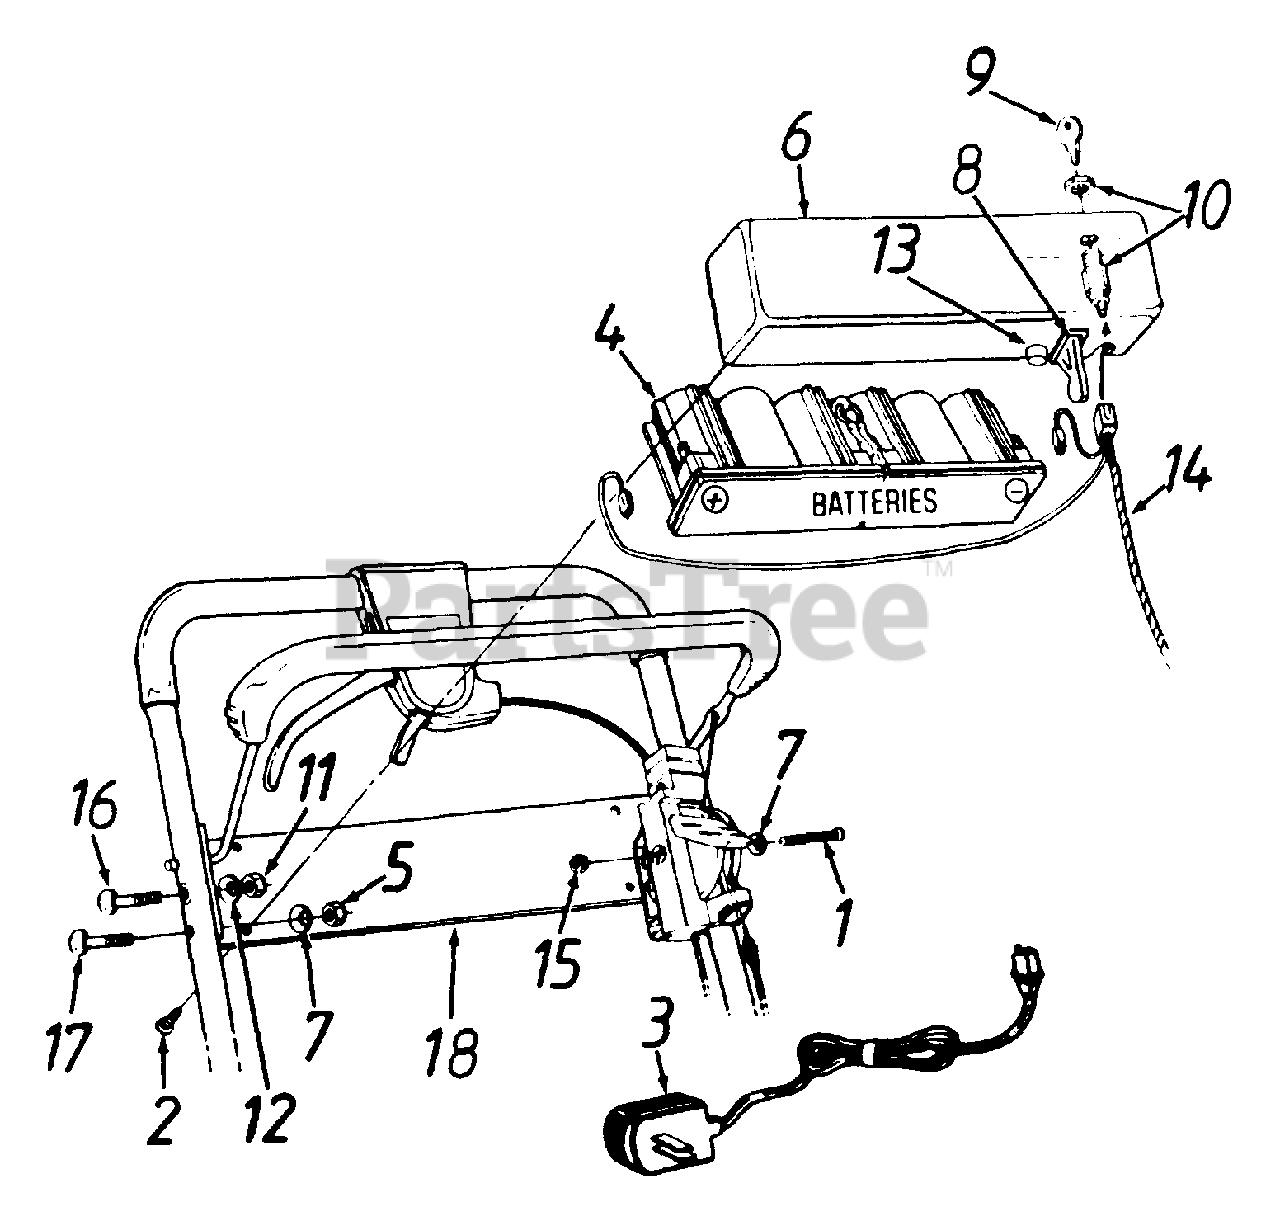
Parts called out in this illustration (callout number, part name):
1	Hex Bolt 1/4-20 x 2" Lg.
2	Truss Mach. Hi-Riser Tap Scr. 1" Lg.
3	Battery Charger
4	Battery Pack - 12 Volt
5	Hex Nut 1/4-20 Thd.
6	Battery Tray
7	Bell-Wash. 1/4" I.D.
8	Plug
9	Ignition Key
10	Ignition Switch
11	Hex Nut 5/16-18 Thd.
12	Bell-Wash. 5/16" I.D.
13	Fuse Holder
14	Wire Harness
15	Hex L-Nut 1/4-20 Thd.
16	Curved Carr. Bolt 5/16-18 x 1.38" Lg.
17	Carr. Bolt 1/4-20 x 1.25" Lg.
